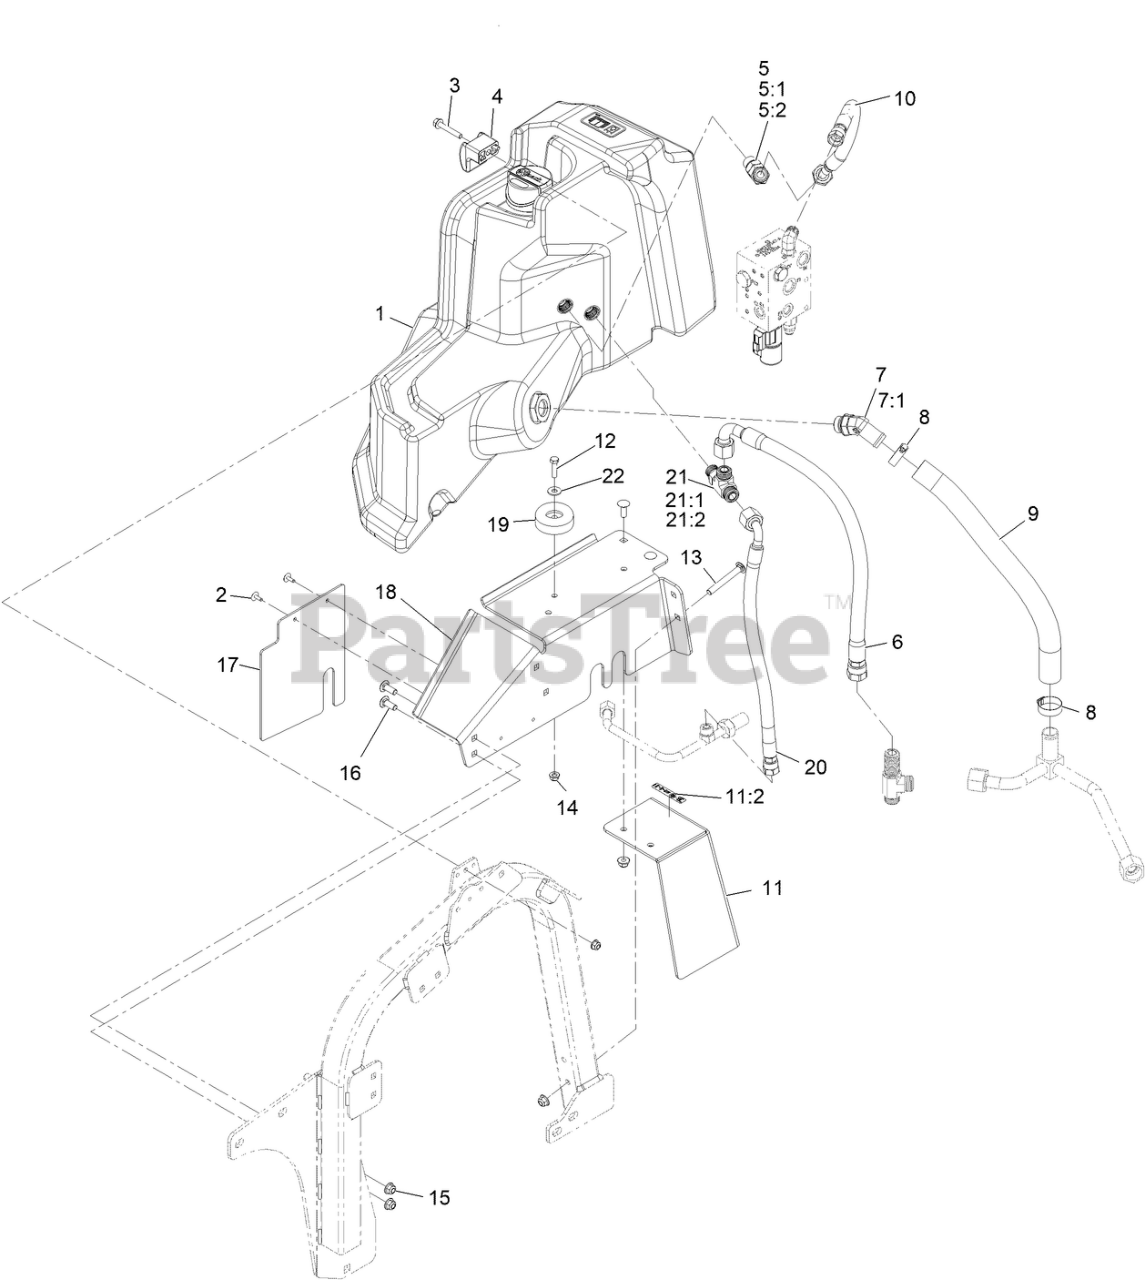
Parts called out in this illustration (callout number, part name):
1	HYDRO TANK ASM W/DECAL
2	RIVET-POP
3	SCREW-HHF
5	FITTING-HYD, 45 DEG
5:1	O-RING
5:2	O-RING
6	HYDRAULIC HOSE ASM
7	FITTING-ELBOW-45
7:1	O-RING
8	CLAMP-HOSE
9	HOSE-SUCTION
10	HYDRAULIC HOSE ASM
11	RH FENDER ASM W/DECAL
11:2	DECAL-TORQUE, WHEEL NUT
12	SCREW-HH
13	SCREW-CARR
14	NUT-HF, NI
15	NUT-HF, NI
16	SCREW-CARR
17	FLAP-COVER, SIDE
18	BRACKET- HYDRAULIC TANK MOUNT
19	BUMPER-RECESS
20	HYDRAULIC HOSE ASM
21	FITTING-TEE
21:1	O-RING
21:2	O-RING
22	WASHER-FLAT
